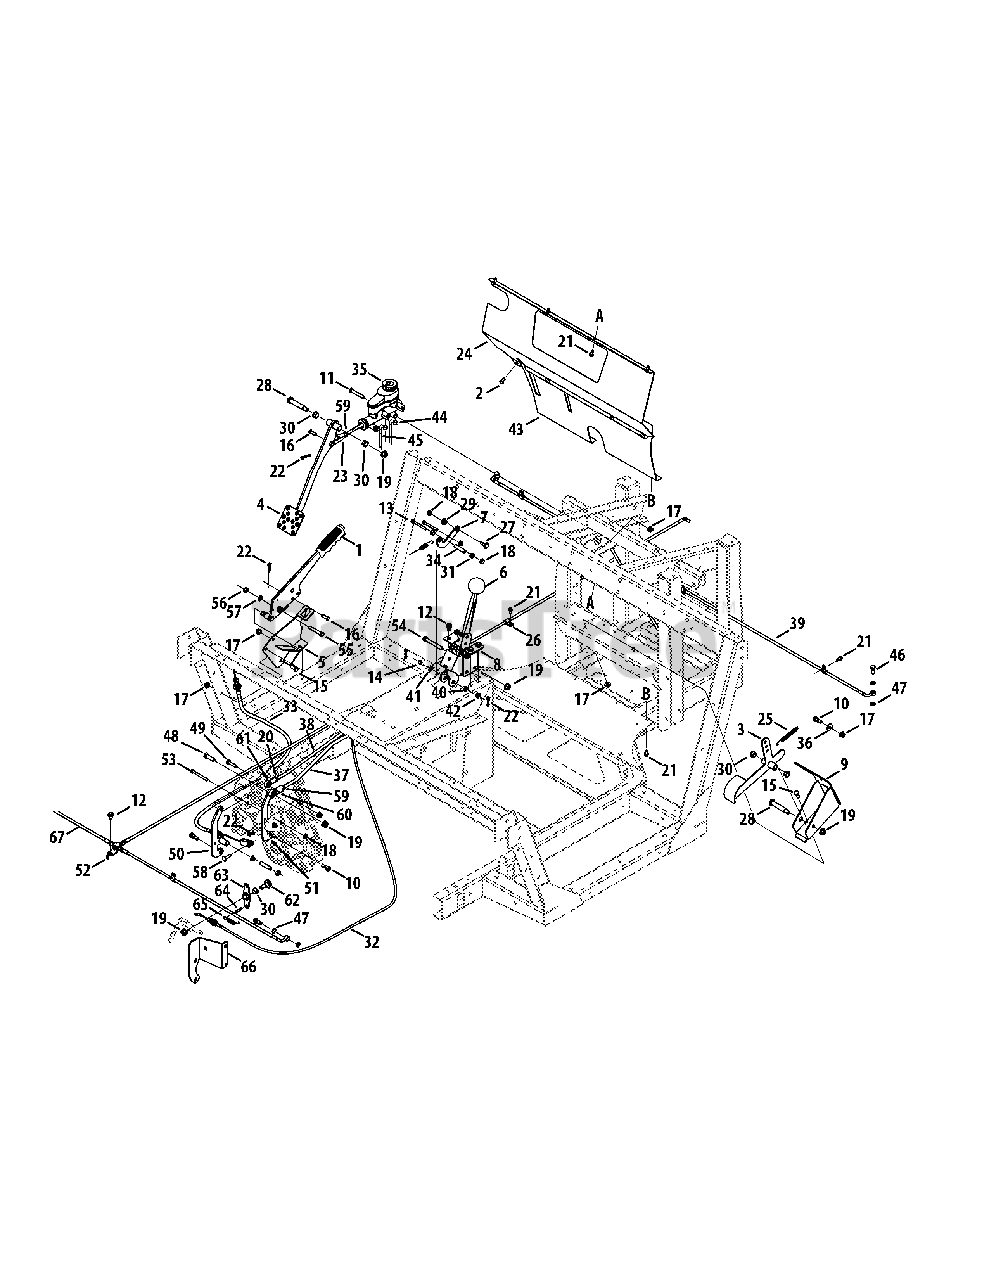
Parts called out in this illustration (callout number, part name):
1	Lever Assembly, Brake
2	Screw, ab, 1/4-14, 0.625,
3	Pedal Assembly, Accelerator
4	Pedal Assembly, Brake
5	Bracket Assembly, Park Brake
6	Shaft Assembly, Hurst, 4x4
6	Shaft Assembly, Hurst, 4x2
7	Plate, Pawl, Over Center
8	Shaft, Console Mount
9	Bracket, Accelerator Pedal
10	Screw, Shldr, .372 x .375, 5/16-18
11	Screw, 5/16-18, 2.00, Gr5, Patch
12	Screw, Tt, 5/16-18, 0.500
13	Screw, 1/4-20, 2.25, Gr5, Std
14	Bearing., Flange, .315 ID
15	Screw, 5/16-18, .75, Gr5, Std
16	Pin, Clevis, 312 Od x 1.0"
17	Nut, Flange Lock, 5/16-18
18	Nut, Flange Lock, 1/4-20, Nylon
19	Nut, Flange Lock, 3/8-16, Nylon
20	Nut, Jam, 5/16-24, Gr5
21	Screw, Tt, 1/4-20 x .500
22	Pin, Cot, 3/32, 1.0
23	Yoke, 5/16-24
24	Panel, Dash, Upper
25	Spring, External, .38 Od x 3.6
25	Spring, External, .49 Od x 3.15
26	Clamp, Hose
27	Screw, Shldr, .375x.380, 1/4-20
28	Screw, Shldr, .500 x 2.230, 3/8-16
29	Plastic Bushing .380 Id
30	Bearing, Flange, .500 x .34
31	Bearing, Flng., .375 x .580 x .250
32	Cable, Cont, Diff, Lock
33	Cable, Cont, Park, Brake, 4x4
34	Spacer, Pivot, Diff Lock
35	Cylinder, Master, Tandem
36	Washer, Flat, .349 x .879 x .063
37	Link, Shaft, F N R
38	Link, Shaft, Hi Lo, 4x4
39	Hose, brake, front
40	Washer, Flat, .385 x .62 x .063
41	Washer, Flat, .330 x .630 x .0635
42	Bearing, Flange, .377 Id
43	Panel, Dash, Lower, 4x4
44	Hose, Brake, Master Cyl, Front
45	Hose, Brake, Master Cyl, Rear
46	Fitting, Banjo Ftg Bolt, M10 x 1.00
47	Fitting, Banjo Ftg Crush Washer
48	Screw, 3/8-16 x 1.25
49	Screw, 5/16-18 x 1.25
50	Lever, Assembly, Shift, Hi-Lo, 4x4
51	Lever, Assembly, Shift, F N R
52	Fitting, Tee, -3, 45 Deg Flare
53	Screw, 1/4-20 x 2.50
54	Screw, 3/8-16 x 2.75
55	Screw, 5/16-18 x 2.00
56	Nut, Hex, 5/16-18
57	Washer, Flat, .344 x .688 x .065
58	Pin, Clevis
59	Nut, Jam, 3/8-24
60	Rod, End, 3/8 ID
61	Rod, End, 5/16 ID
62	Screw, shldr, .500 dia x .434
63	Lever, Assembly, Diff Lock
65	Spring, external, .38od x 2.10
66	Bracket, diff, Cable,mnt
67	Hose, brake, rear
